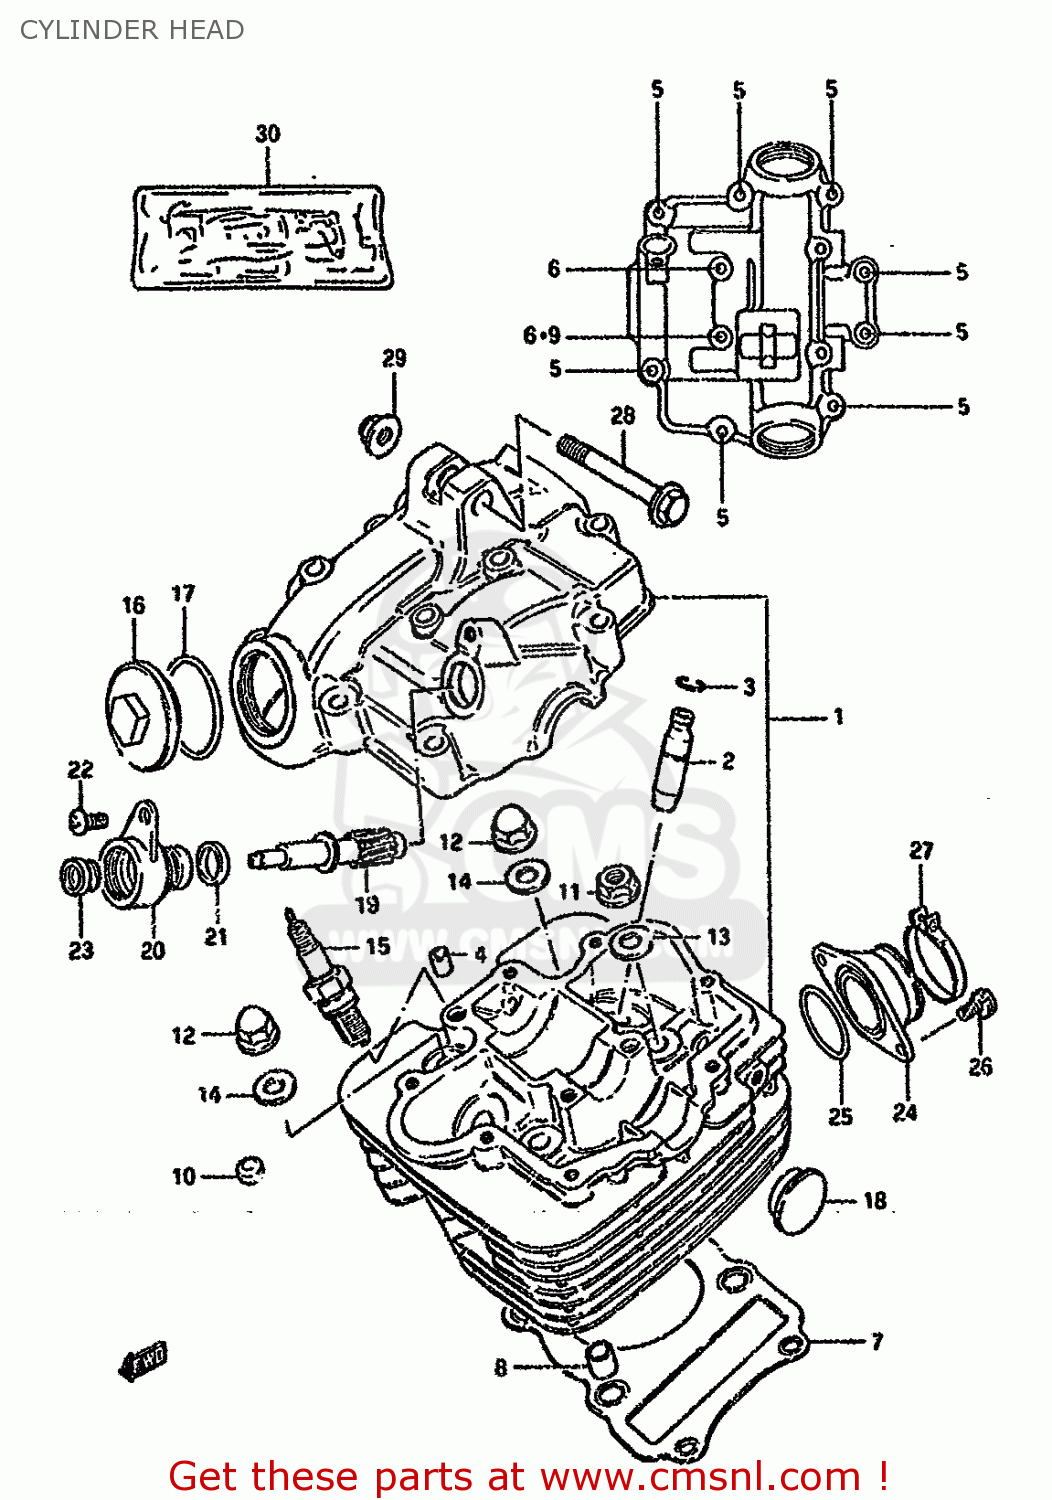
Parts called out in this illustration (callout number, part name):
1	HEAD ASSEMBLY,CYLINDER
2	GUIDE,VALVE
3	RING,SNAP
4	PIN(6.2X8X11)
5	BOLT
6	BOLT
7	GASKET,CYLINDER HEAD (NAS)
8	PIN
9	GASKET(5.8X13X1.2) (NAS)
10	PAD,CYLINDER HEAD
11	NUT
12	NUT
13	WASHER(8.5X19X2.3)
14	GASKET (NAS)
15	SPARK PLUG
16	CAP,INSPECTION HOLE
17	O RING(D:3,ID:29.5)
18	PLUG(OD:22.5)
19	GEAR,TACHOMETER DRIVEN
20	SLEEVE,TACHOMETER DRIVE GEAR
21	SEAL,TACHOMETER DRIVEN
22	SCREW
23	SEAL,OIL(5X12X8)
24	PIPE,INTAKE
25	O RING(D:2.4,ID:31.7)
26	SCREW
27	CLAMP
28	BOLT(8X50)
29	NUT
30	GASKET SET (NAS)
